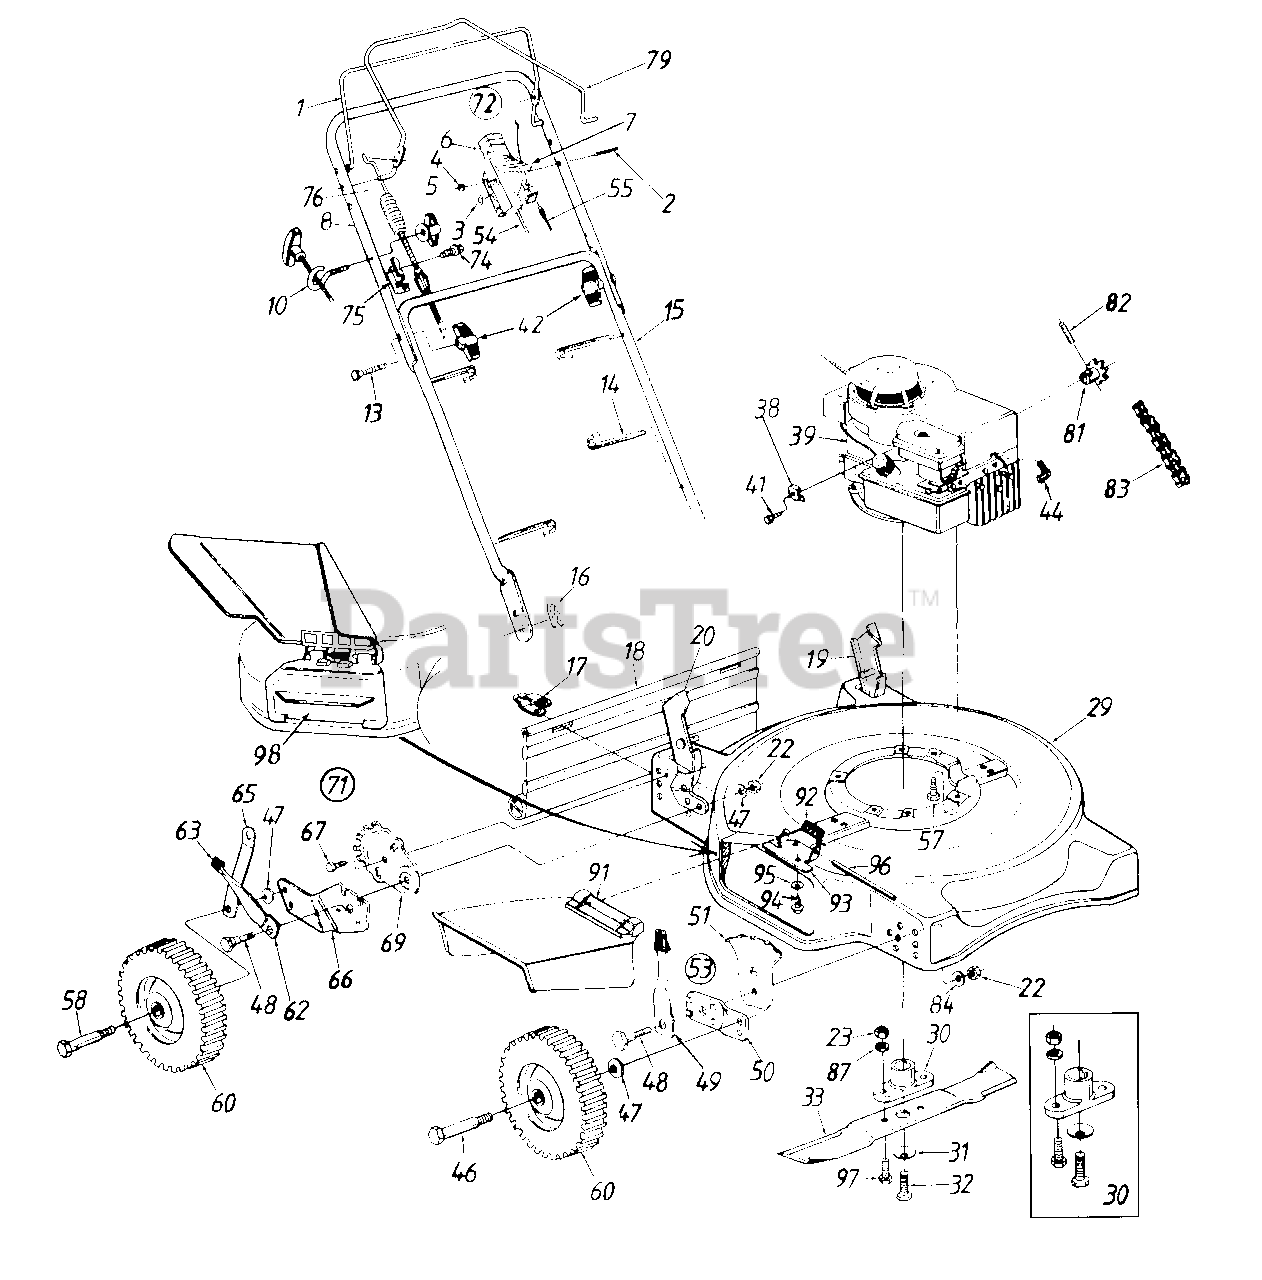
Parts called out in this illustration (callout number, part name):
2	Oval C-Sunk Mach. Scr.
3	Spr. Wash. .66" I.D.
4	Hex L-Nut 1/4-20 Thd.
5	Handle Knob 1/4-20 Thd.
6	Throttle Body
7	Throttle Lever
13	Curved Hd. Bolt 5/16-18 x 2" Lg.
14	Cable Tie
16	Hairpin Cotter
17	Hinge Clip
18	Rear Flap
23	Hex Nut 3/8-24 Thd.
29	22" Deck Ass'y.
30	Blade Adapter Kit
31	Bell-Wash. .39" I.D.
32	Hex Bolt 3/8-24 x 1.5" Lg.
33	22" Blade
38	Cable Clamp (B&S)
39	Engine
41	Hex Wash. Hd. Scr. #10-32 x .62" Lg. (B&S)
42	Hand Knob
44	Spark Plug Boot
46	Front Axle Bolt
47	Bell-Wash. .400" I.D. x .88"
48	Shld. Bolt .50" Dia. x .357"
49	Spring Lever Ass'y. w/Knob
51	Height Adj. Plate
53	Height Adj. Ass'y. Comp. - R.H.
54	Throttle Control Wire - 51" Lg. (B&S)
55	Control Cable - 39" Lg. (B&S)
57	Hex L-Wash. Hd. Scr. 3/8-16 x 1.0" Lg.
58	Rear Axle Bolt
60	Wheel Ass'y. Comp.
62	Spring Lever
63	Spring Lever Knob
67	Hex L-Wash. Hd. AB-Tap
69	Index Plate
71	Rear Height Adj. Ass'y. - R.H.
72	Throttle Box Comp.
74	Hex Wash. AB-Tap Scr. 5/16 x .75" Lg.
75	Cable Brkt.
76	Clutch Cable
82	Spring Pin Spir. 3/16" Dia. x 1" Lg.
83	#48 Chain 1/2" Pitch 50 Links (Endless)
84	Bell-Wash. .39" I.D. x 1.38"
87	L-Wash. 3/8" I.D.
91	Chute Deflector Ass'y.
92	Torsion Spring
93	Adapter Plate
94	Hex Self-Tap Scr. 1/4-20 x .5" Lg.
95	Bell-Wash. 1/4" I.D.
96	Hinge Pin
97	Hex Bolt 3/8-24 x 1" Lg.
98	Mulching Plug
